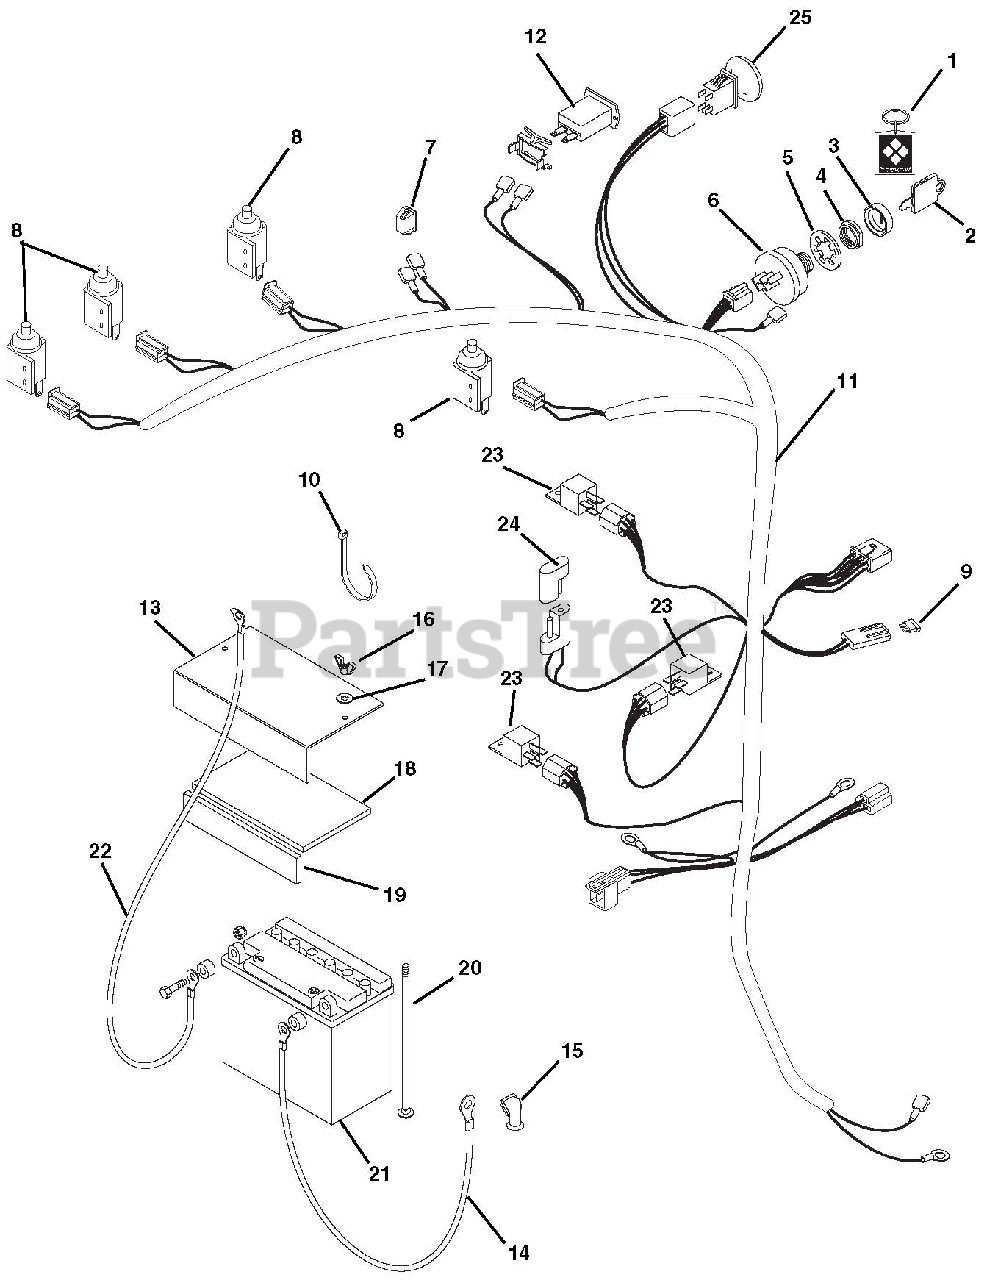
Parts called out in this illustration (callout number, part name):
1	Key Chain
2	Ignition Switch Key
3	Cap, Ignition Switch
4	Nut, Panel .625-32
5	Washer-Lock .625 Internal Tooth
6	Key Switch
7	Light, Indicator
8	Single-Pole N.O. with Cover
9	Fuse-30 AMP
10	Tie Wrap-Black
11	Wire Harness, Pro-300
12	Hour Meter
13	Cover-Battery
14	Cable-Battery
15	Boot, Insulator
16	Nut-Locking-Wing .25-20
17	Washer-Flat-Steel .281 x .625 x .065
18	Pad, Battery
19	Pad, Battery
20	Bolt-Round Head Square Neck .25-20 x 7.00 Grade 2
21	Battery, 12 Volt
22	Cable, Negative Battery
23	Relay
24	Molded Diode Plug 1 AMP
25	Switch, Clutch With Retainer
